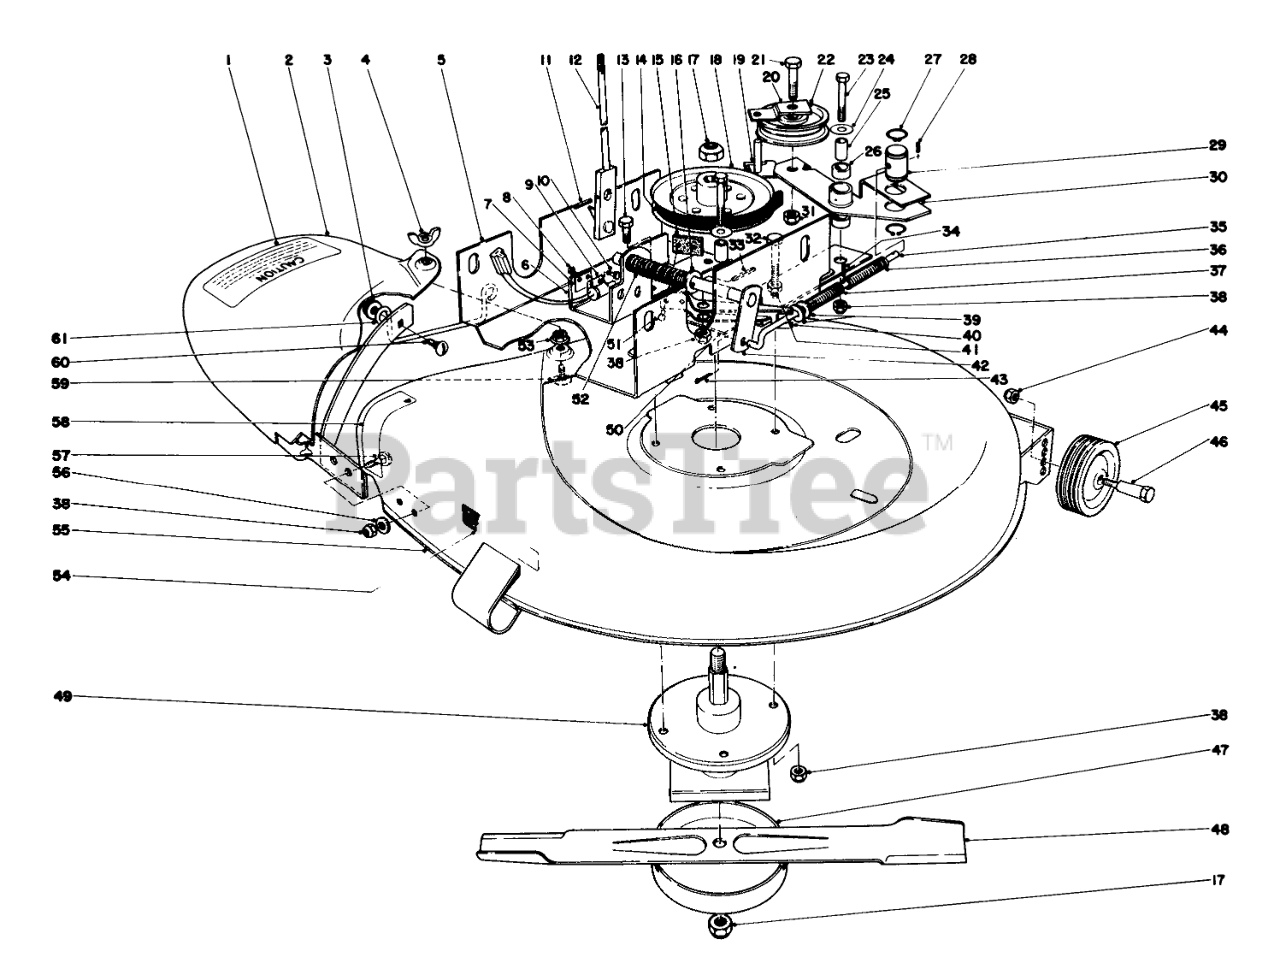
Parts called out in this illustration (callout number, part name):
1	Decal
2	DEFLECTOR WA R
3	NUT-LOCK, HHF
4	Wing Nut
5	CHANNEL HT ADJ R
6	Mounting Bracket Blade
7	Spacer Switch
8	NUT-KEPS
9	DECK INTERLOCK SWITCH
11	PIN-SPIRAL
12	Lever Deck Engagement
13	SCREW-HH
14	V-BELT
15	BLADE BRAKE LINING
16	WASHER-FLAT
18	DECK PULLEY R
19	Belt Retainer
20	BELT RETAINER UPPER
21	SCREW-HH
22	Flat Idler
23	SCREW-HH
24	WASHER-PLAIN
25	PIVOT SPACER
26	Bushing
27	RING-RETAINING
28	PIN-ROLL
29	Pin-Pivot
30	Idler Arm (Incl. Ref. #26)
31	NUT-LOCK, SIDE
32	SCREW-HH
33	PIN-SPRING
34	PIN-SPRING
35	BLADE ENGAGE ROD
36	Spring Deck Idler
37	Spring Deck Brake
38	NUT-LOCK, CONE
39	WASHER
40	Blade Brake (Incl. Ref. #15 & 51)
41	NUT-JAM
42	Linkage
43	PIN-COTTER
44	Nut
45	Wheel
47	Cup
48	Blade
49	Mower Spindle
50	Bracket Idler Mounting
51	Rivet
52	COMP SPRING O
53	PAL NUT
54	Decal-Deck Inst.
55	HOUSING WA R
56	WASHER-FLAT
57	BOLT-CARR
58	Decal Housing
59	Carriage Bolt
60	SCREW-CARRIAGE
61	Bracket Foot Guard
